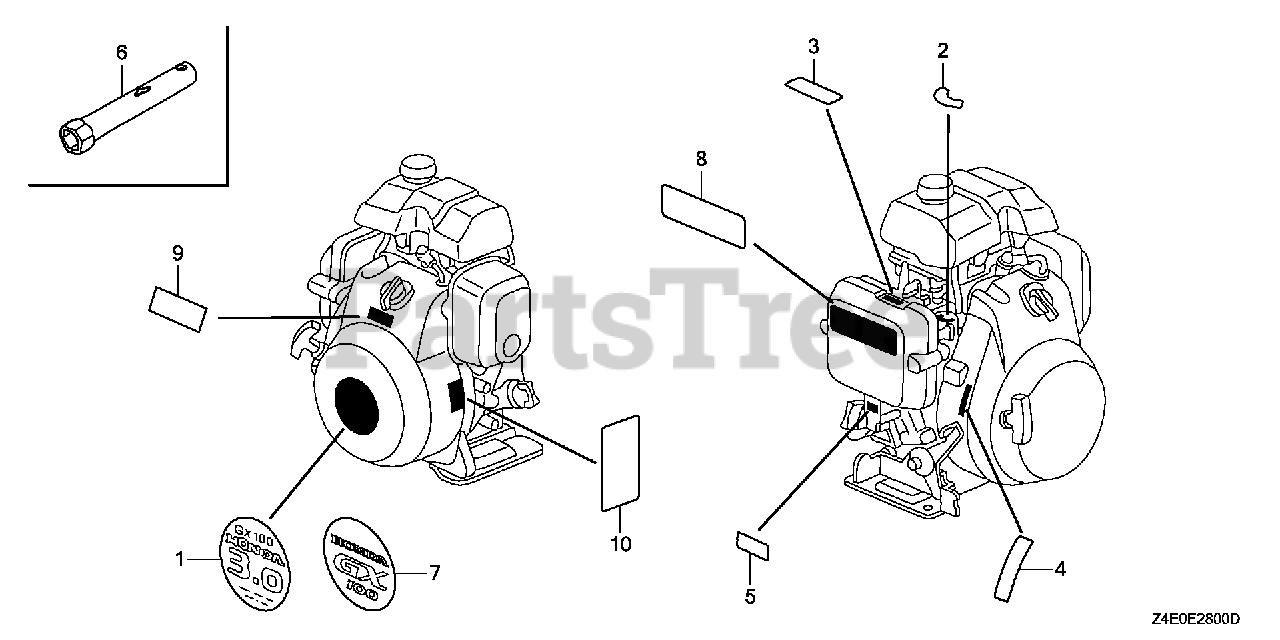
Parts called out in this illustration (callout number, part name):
1	EMBLEM (GX100)
2	MARK, PETCOCK (EXTERNAL)
3	MARK, CHOKE INDICATION
4	MARK, THROTTLE INDICATION
5	MARK, TYPE (QXB4)
7	EMBLEM (GX100) (RAMMA)
7	EMBLEM (GX100)
8	MARK, OPERATOR CAUTION (ENGLISH)
8	MARK, OPERATOR CAUTION (FRENCH)
8	MARK, OPERATOR CAUTION
9	MARK, EX. CAUTION (ENGLISH)
9	MARK, EX. CAUTION (FRENCH)
